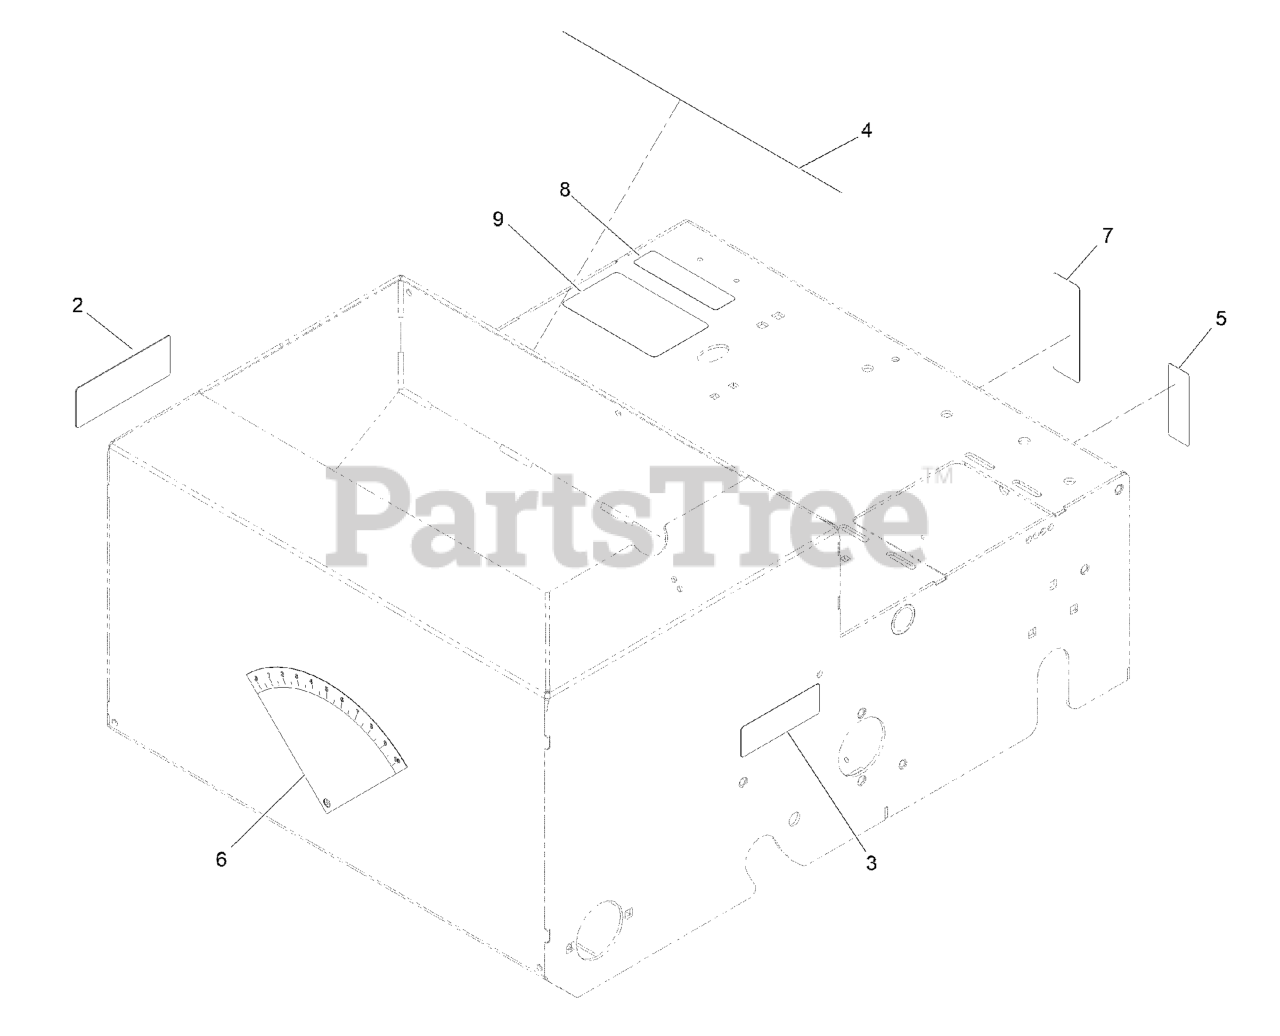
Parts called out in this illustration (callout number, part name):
2	DECAL-DANGER
3	DECAL-WARNING
4	DECAL-WARNING
5	DECAL-BRAKE, PARKING
6	DECAL-FLOW, SEED
7	DECAL-BYPASS
8	DECAL-ARRESTOR, SPARK
9	Decal-Service Aid Seeder
